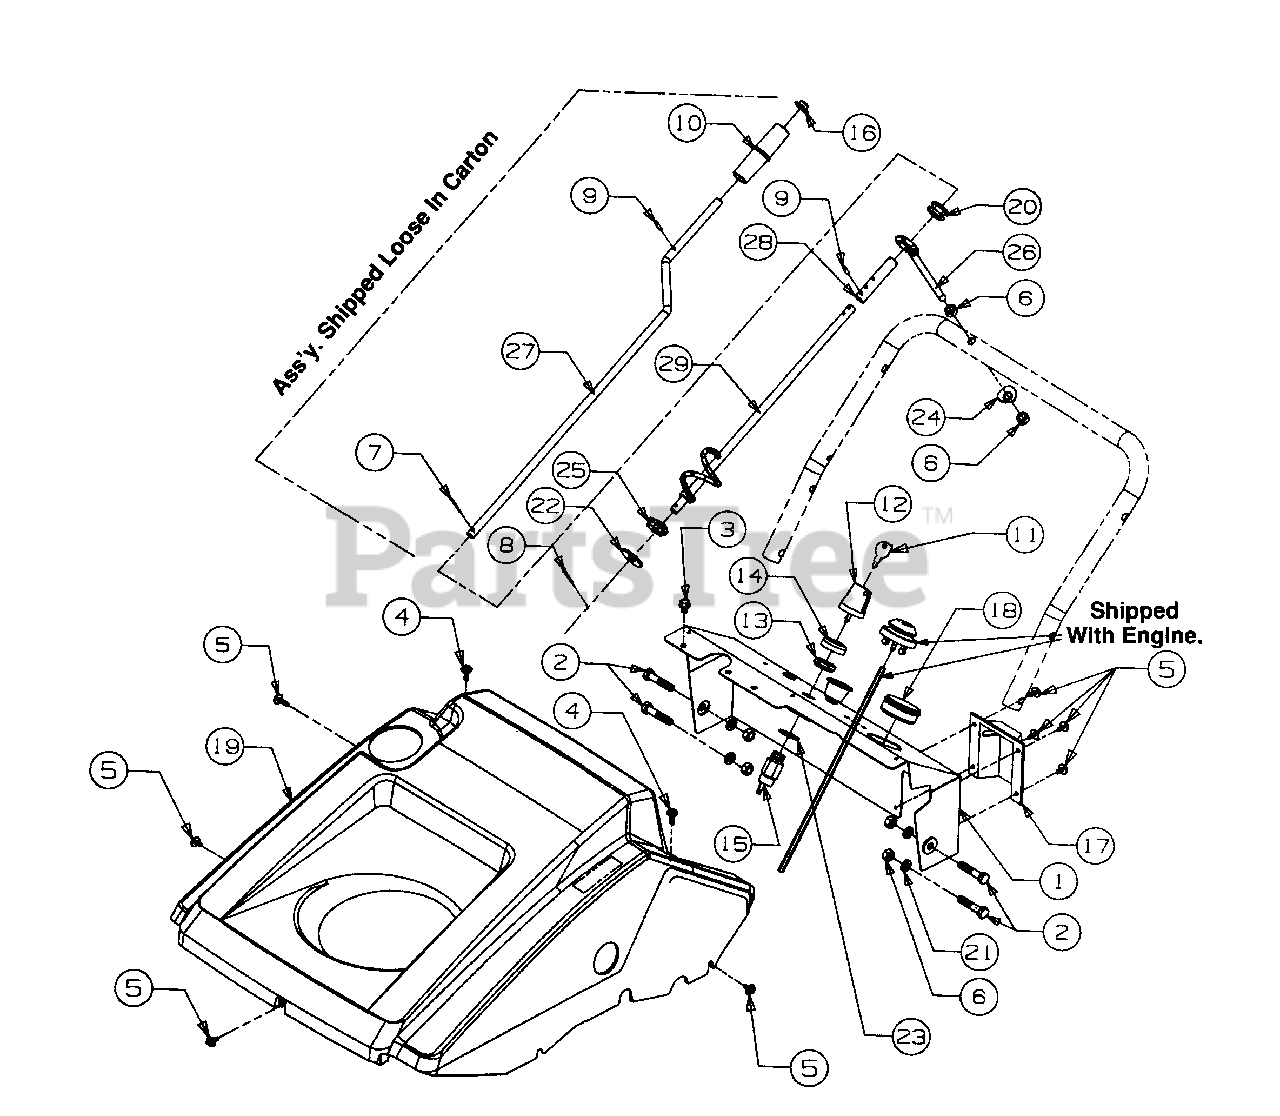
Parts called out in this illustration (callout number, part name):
2	Screw - Hex Cap
3	Screw - Hex Washer
4	Screw - Hex
5	Screw - Hex
6	Nut - Hex
7	Pin - Cotter
8	Pin - Cotter
9	Pin - Roll
11	Key - Ignition
12	Key - Ignition with Logo
13	Nut - Ignition Switch
14	Cover - Ignition Switch
15	Switch - Key
16	Cap - Push
17	Cover - Choke
18	Plug - Insert
19	Shroud - Yellow
20	Grommet - Rubber
21	Washer - Lock
22	Washer - Flat
23	Washer - Lock Internal
24	Washer - Saddle
25	Bushing - Hex
26	Eyebolt - Chute Crank
28	Spacer
29	Crank - Chute Lower
